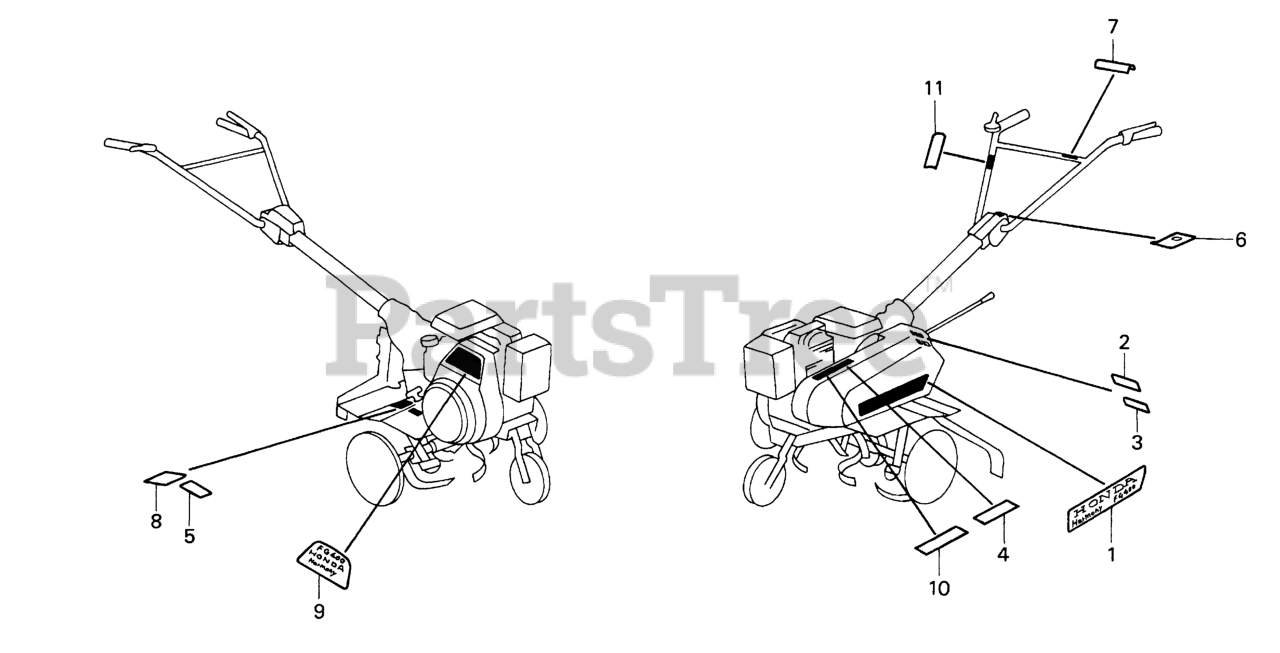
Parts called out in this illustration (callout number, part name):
1	MARK, EMBLEM (FG400/HARMONY)
4	LABEL, BELT WARNING (ENGLISH)
5	LABEL, TINE DANGER
6	MARK, ENGINE SWITCH (ENGLISH)
7	MARK, MAIN CLUTCH INDICATION
8	LABEL, OPERATOR WARNING (ENGLISH)
9	EMBLEM (FG400/HARMONY)
10	LABEL, HEAT WARNING (ENGLISH)
11	MARK, HOLD POSITION (U.S.A. LABEL)
